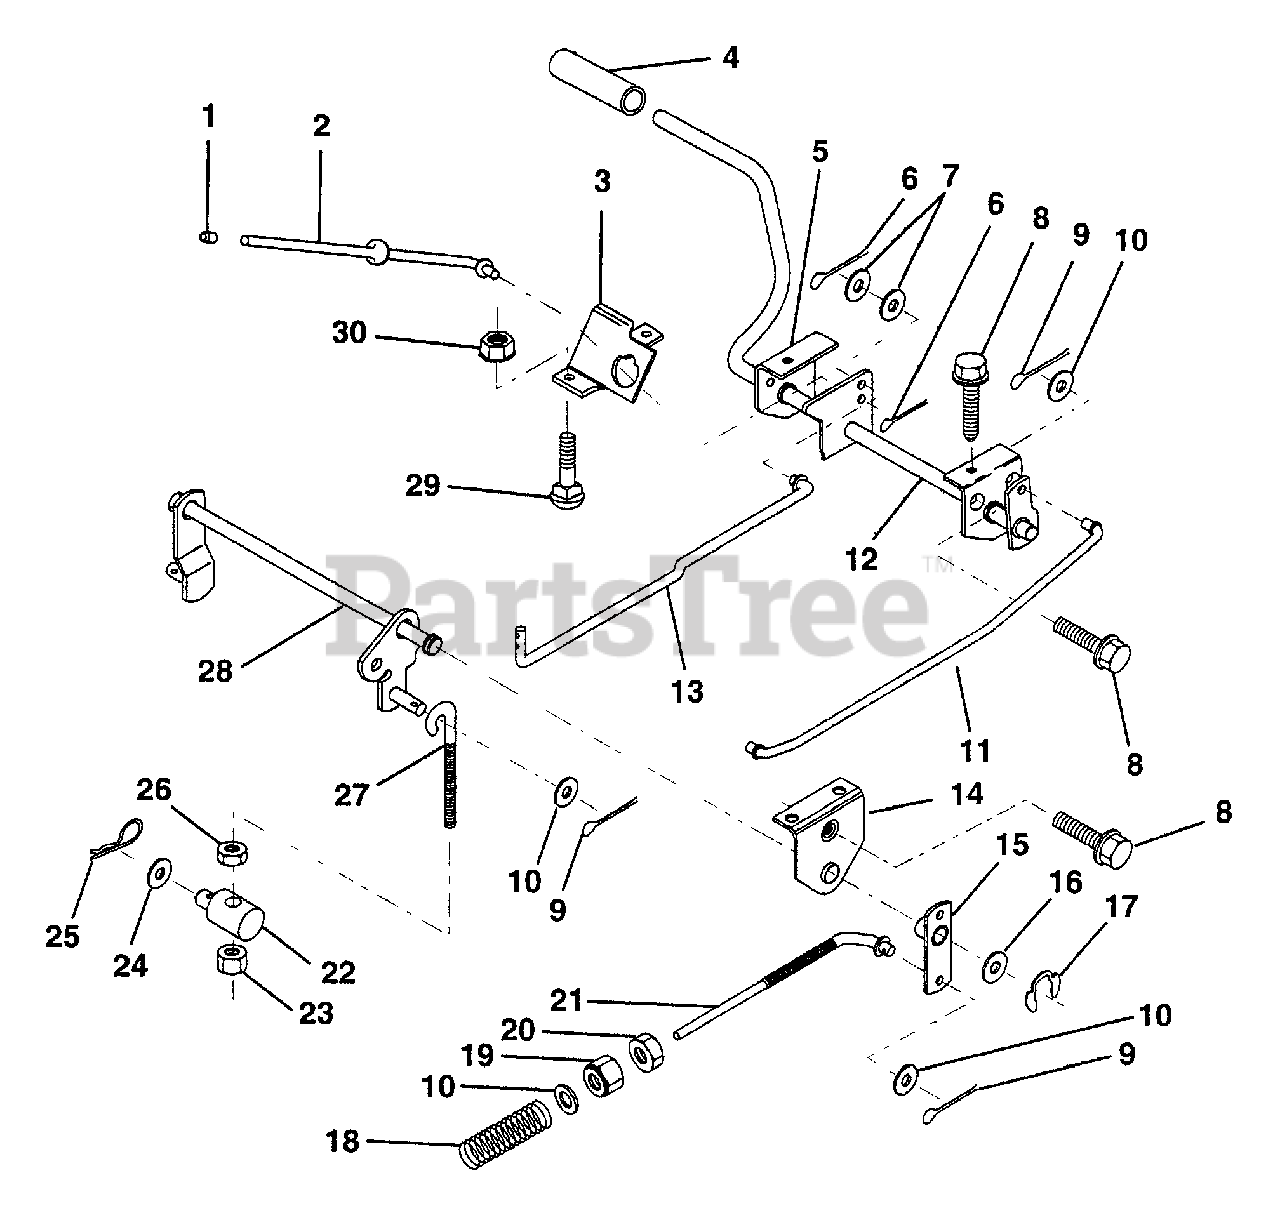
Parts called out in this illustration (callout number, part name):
1	Cap, Plunger
2	Rod, Parking Brake
3	Bracket, Parking Brake
4	Cover, Pedal
5	Bracket, Clutch/Brake Pedal, L.H.
6	Pin, Cotter 3/32 x 3/4
7	Washer 13/32 x 5/8 x 16 Gauge
8	Screw, Hex Head, Thd., Roll. 5/16-18 x 1/2
9	Pin, Cotter 1/8 x 3/4
10	Washer 13/32 x 13/16 x 16 Ga.
11	Rod, Brake Front
12	Assembly, Clutch/Brake Pedal
13	Rod, Clutch
14	Bracket, Lift, Shaft
15	Assembly, Brake, Pivot, Arm
16	Washer 25/32 x 1-1/8 x 16 Ga.
17	Ring, Klip
18	Spring, Brake Rod
19	Nut, Crownlock 3/8-16
20	Nut, Hex, Jam 3/8-16 UNC
21	Rod, Rear, Brake
22	Trunnion, Lift
23	Nut, Crownlock 3/8-16 UNC
24	Washer 13/32 x 1-1/4 x 12 Ga.
25	Spring, Retainer
26	Nut, Centerlock 3/8-16 UNC
27	Link, Threaded
28	Assembly, Rear Mower Lift
29	Bolt, Carriage 5/16-18 UNC x 3/4
30	Nut, Hex, Keps 5/16-16 UNC
